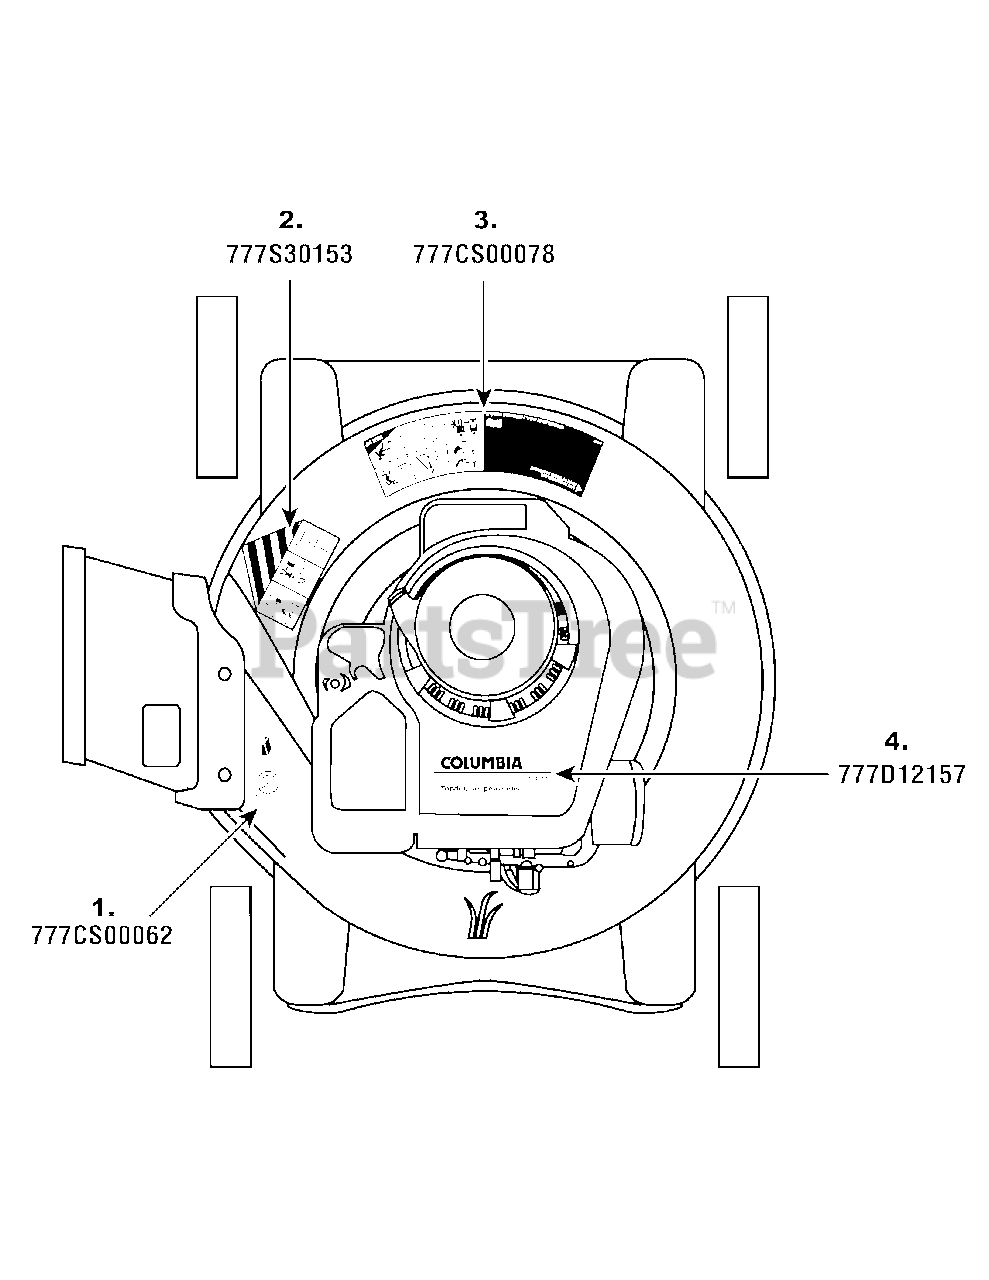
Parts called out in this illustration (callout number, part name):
1	LABEL-INSTALL CHUTE
2	LABEL-DANGER CHUTE
3	LABEL-MWR DNGR CRVD
4	LABEL-ENG SHROUD COLUMBIA
